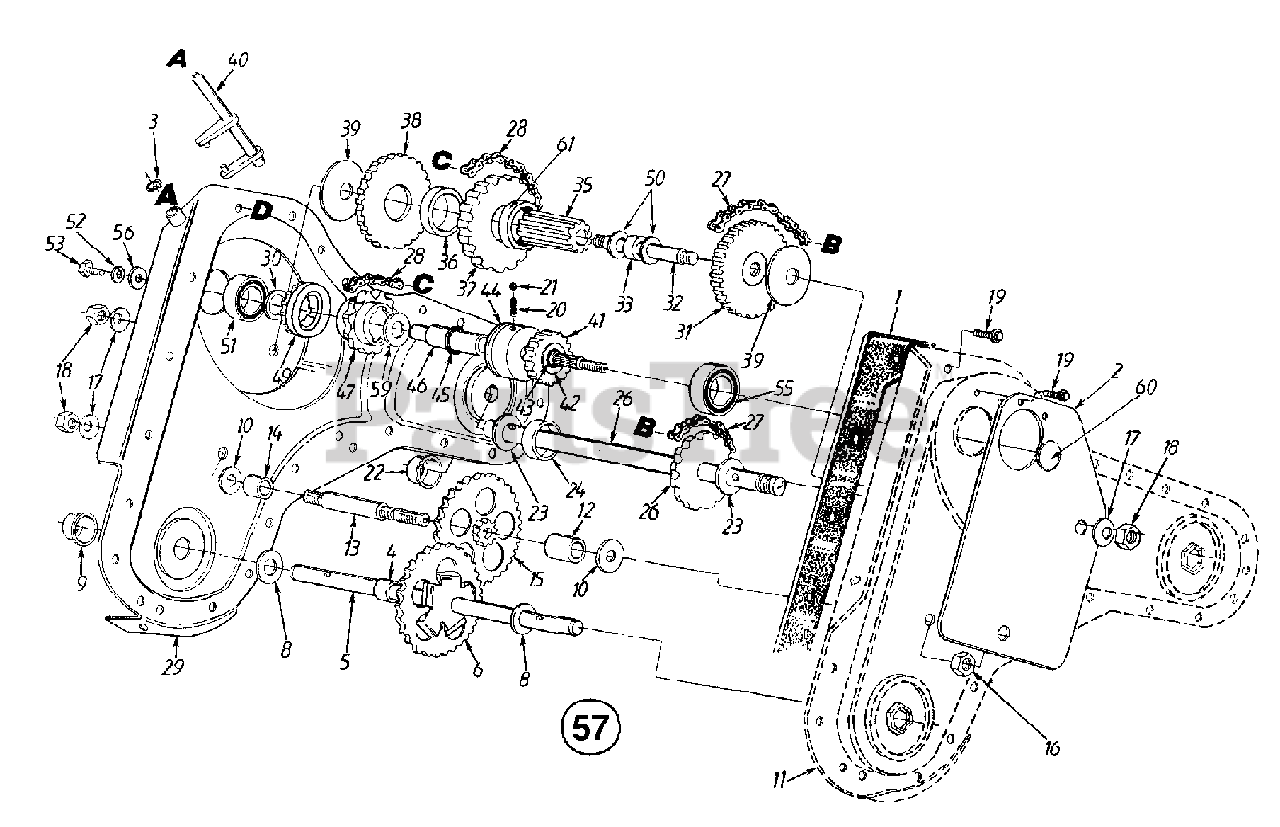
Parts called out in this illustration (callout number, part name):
1	Chain Case Gasket
3	Snap Ring
4	Spacer .735" I.D. x .886" O.D.
5	Wheel Shaft
6	Spur Gear 46T
8	Fl-Wash. .76" I.D. x 1.5" O.D.
9	Shaft Seal
10	Thr.Wash. .445 I.D. x 1.92 O.D. x .060
13	Jack Shaft 2.06" Lg.
14	Spacer .635" I.D. x 1" O.D. x .37" Thk.
15	Gear Idler Ass'y.
16	Hex Patch L-Nut 7/16-20 Thd.
17	Bell-Wash. .45" I.D. x 1" O.D.
18	Hex Nut 7/16-20 Thd.
19	Hex Wash. Hd. TT-Tap Scr. 1/4-20 x .5" Lg.
20	Spring Detent
21	Ball Detent
22	Shaft Seal
23	Thrust Wash. 1.03" I.D. x 1.62"
24	Spacer 1" I.D. x 2" O.D. x .5" Thk.
26	Tine Shaft Ass'y.
27	Chain #50 5/8" Pitch x 52 Links-Endless
28	Chain-#41 1/2" Pitch x 30 Links-Endless
30	Fl-Wash. 7/16" I.D. x 1-3/8" O.D.
31	Gear and Sprocket Ass'y.
32	Jack Shaft 5" Lg.
33	Spacer .636" I.D. x .86" O.D.
35	Spur Gear 10T
36	Spacer 1.5" I.D. x 1.76" O.D.
37	Sprocket-#41 Chain
38	Reverse Gear 46T
39	Thrust Wash. .445" I.D. x 1.92"
40	Shifter Ass'y.
41	Spur Gear 17T
42	Fl-Wash. .69" I.D. x 1.06" O.D.
43	Wire Ring
44	Clutch Collar
45	Retaining Ring .875" Shaft
46	Drive Shaft
47	Sprocket 11T
49	Spur Gear 16T
50	Fl-Wash. 5/8" I.D. x 1" O.D.
51	Ball Bearing .669" I.D.
52	L-Wash. 1/4" I.D.
53	Hex Bolt 1/4-20 x .62" Lg.
55	Ball Bearing
56	Fl-Wash. .281" I.D. x .875" O.D.
57	Gear Case Ass'y. Comp.
59	Fl-Wash. .88" I.D. x 1.5" O.D.
60	Button Plug
61	Spacer 1.52" I.D.
